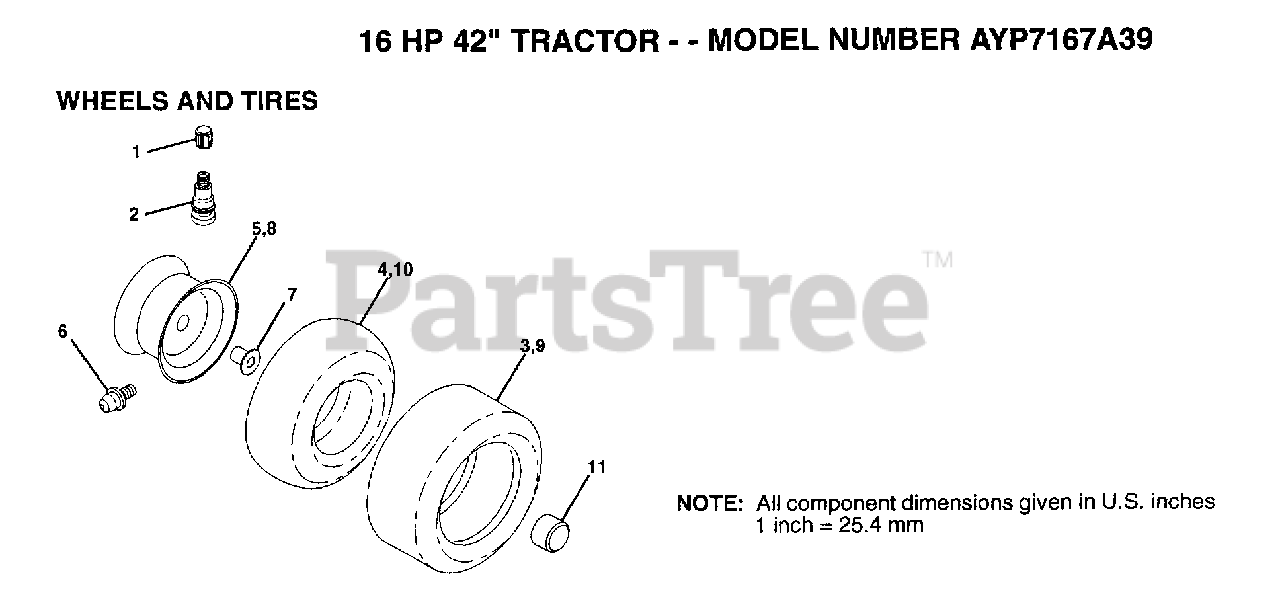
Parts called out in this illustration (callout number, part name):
1	VALVE CAP
2	VALVE STEM LT
4	TUBE.5.3/4.5/6
6	FITTING LT
7	"FLANGE, BEARING"
10	TUBE.18X9.5-8
11	HUB CAP
